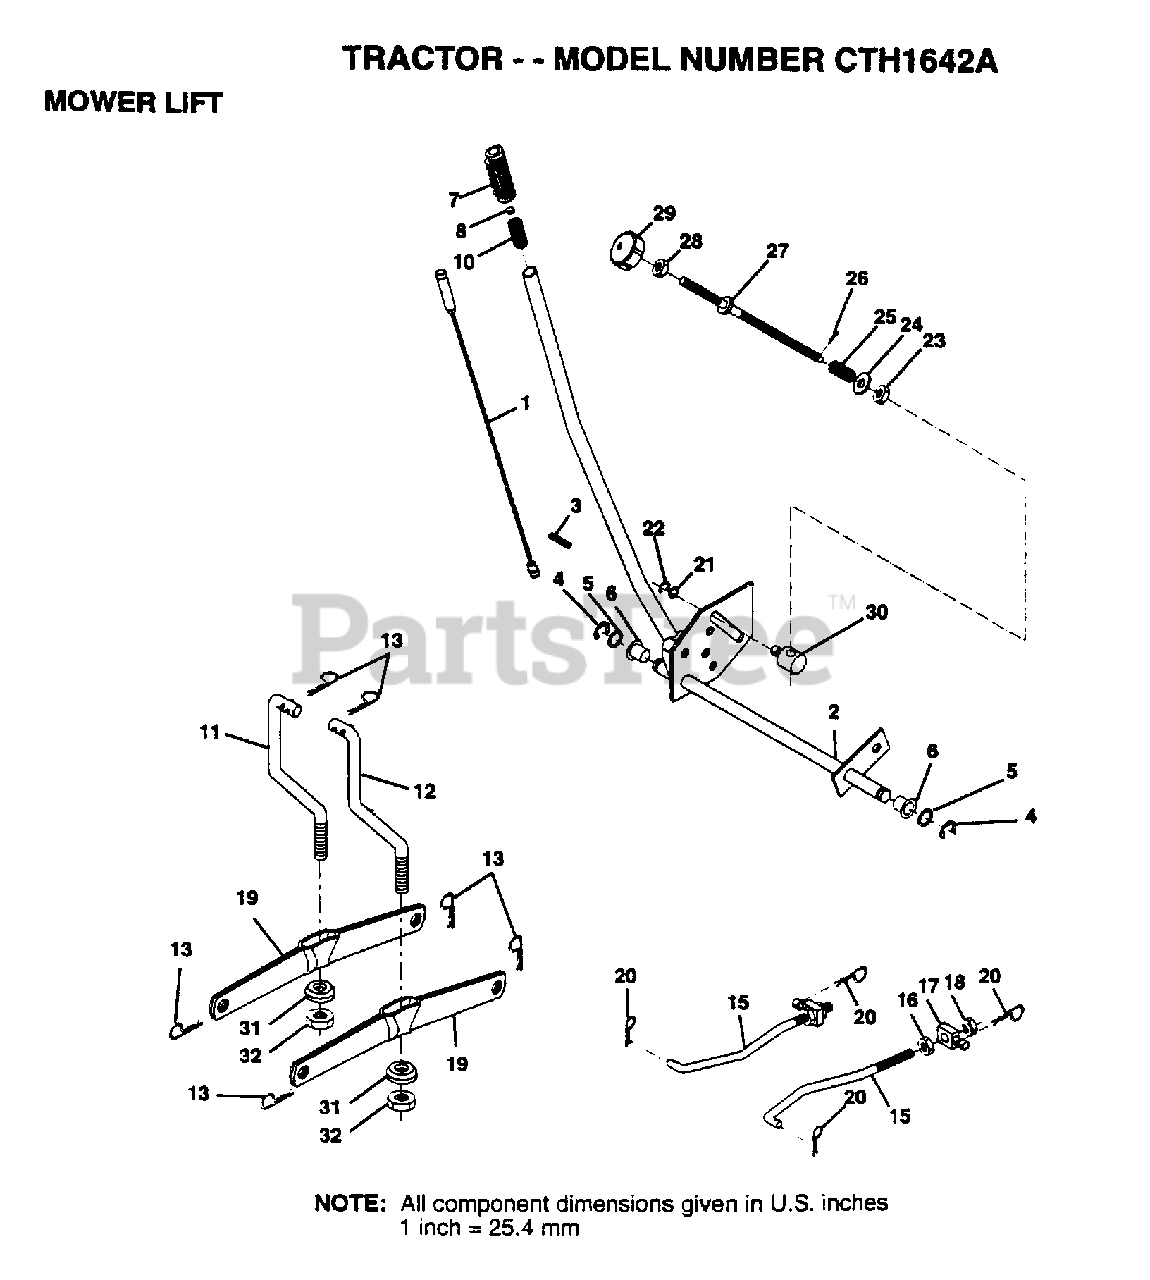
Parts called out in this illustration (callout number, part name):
1	WIRE ASM
2	SHAFT.ASM.LIFT LH
3	PIN GROOVE
5	WASHER
6	NYLON BEARING
7	GRIP
15	LINK.FRONT
16	NUT
17	TRUNION
18	NUT.LK.W/WSH.1/2.
19	ARM SUSP REAR
20	RETAINER.SPRING
21	WASHER
22	KLIP RING
23	NUT T
24	WASHER
25	SPRING.COMP.INF.H
27	ROD.ADJ.LIFT
28	NUT
29	KNOB INF 3/8-16
30	TRUNION LT
31	BEARING PVT LH
32	NUT.CROWNLOCK.3/8
